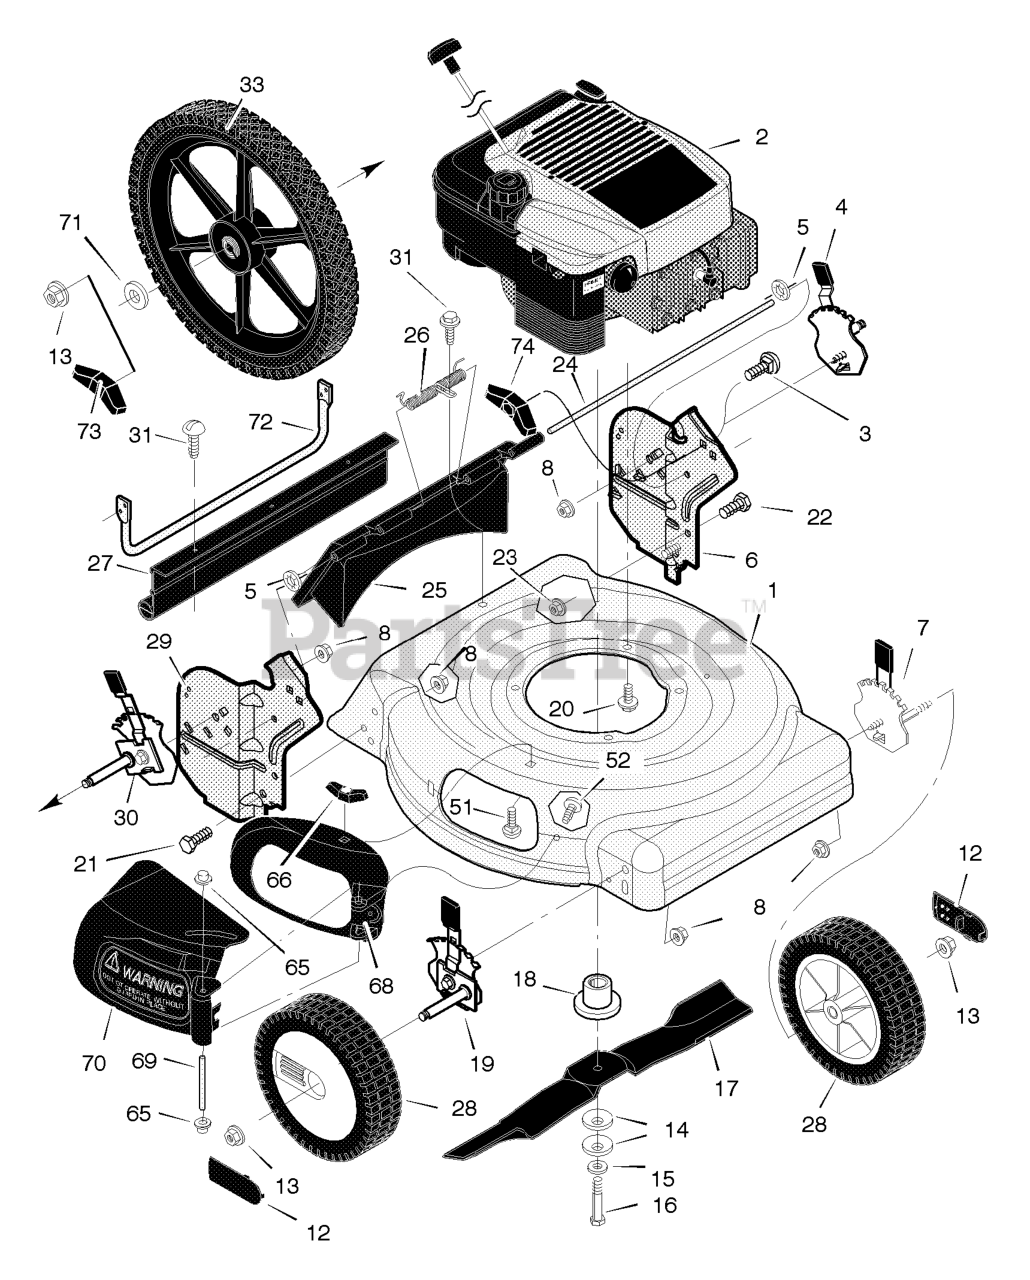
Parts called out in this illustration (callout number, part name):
1	Housing
2	Engine
3	Bolt, Carriage
4	Adjuster, Left Rear Height
5	Retainer, Push
6	Bracket, Left Handle
7	Adjuster, Left Front Height
8	Nut, Flange
12	Hub Cab
13	Nut, Flange
14	Washer, Belleville
18	Adapter, Blade
19	Adjuster, Right Front Height
20	Bolt, Engine
21	Bolt
22	Bolt
23	Nut, Flange
24	Rod, Pivot
25	Door, Rear (Gray)
26	Spring
27	Guard, Rear
28	Wheel & Tire
29	Bracket, Right Handle
30	Adjuster, Right Rear Height
33	Wheel, Rear
51	Bolt, Carriage
65	Push On Cap
66	Wingnut
68	Bezel (Gray)
69	Pin, Pivot
70	Deflector, Chute (Gray)
